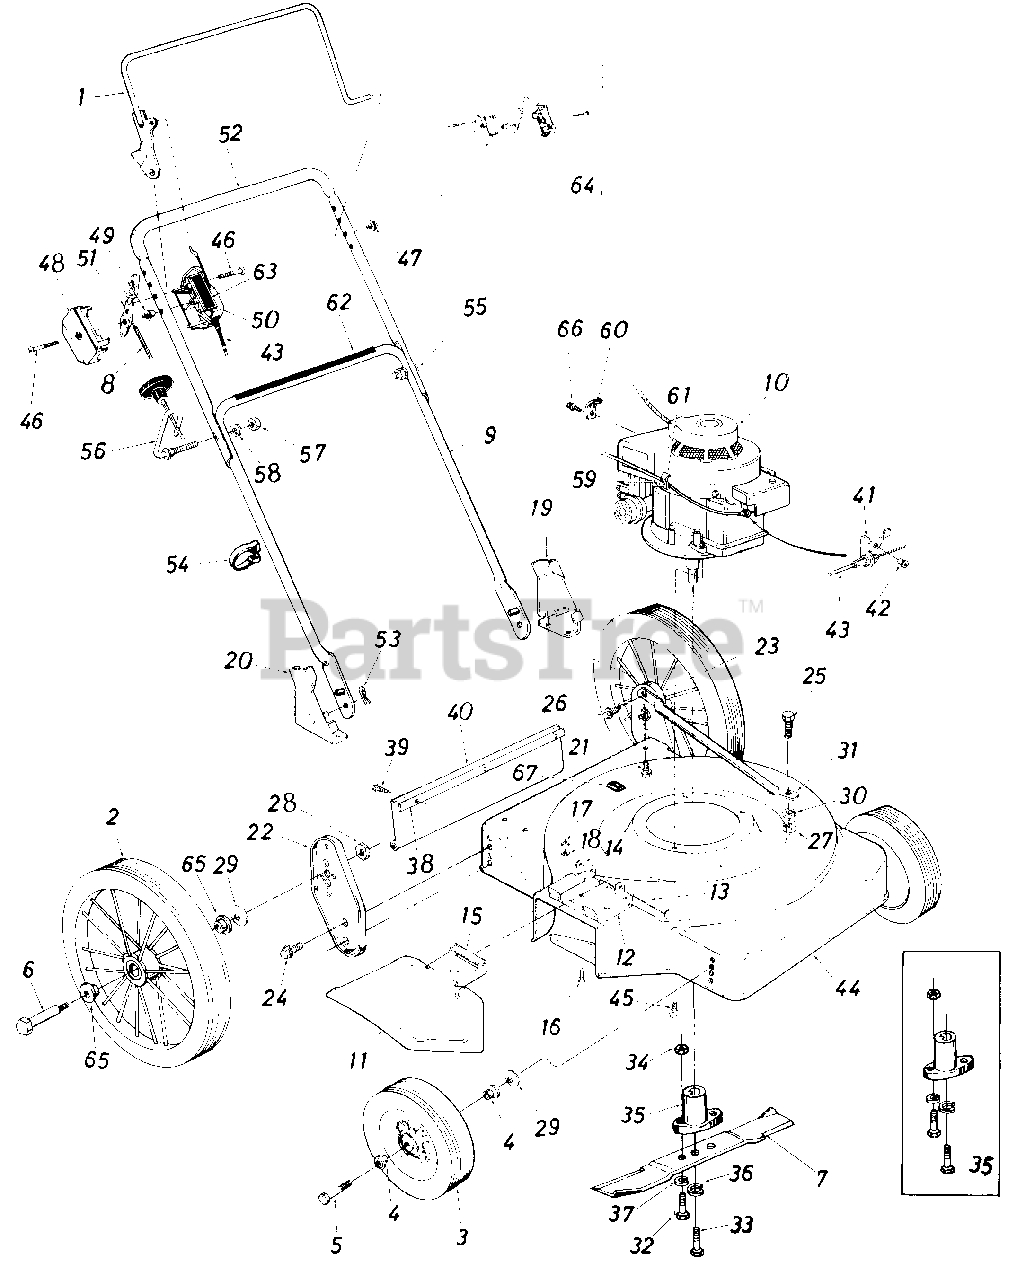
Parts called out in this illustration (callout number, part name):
1	Control Handle Ass'y.-R.H.
2	Rear Wheel Ass'y.-Comp. 14.0 x 1.75
4	Bearing
5	Axle Bolt-Front
6	Shoulder Bolt .50" Dia. x 2.62
7	22" Blade
8	Throttle Wire-43" Lg.
9	Lower Handle (Chrome)
10	Engine
11	Chute Deflector Ass'y.-Comp.
12	Adapter Plate
13	Pivot Pin
14	Push Nut 1/4" Rod
15	Torsion Spring
16	Hex Bolt 1/4-20 x .50" Lg.
17	Hex Nut 1/4 -20 Thd.
18	L-Wash. 1/4" I.D.
19	Handle Mount Brkt.-L.H.
20	Handle Mount Brkt.-R.H.
21	Hex Wash. Hd. "B" Tap Scr. 5/16-18 x .50" Lg.
22	Extension Brkt.-R.H.
23	Extension Brkt.-L.H.
24	Hex Sems Bolt 3/8-16 x .62"
25	Hex Bolt '14-20 x .62" Lg.
26	Hex Wash. Hd. "B" Tap Scr. 5/16-18 x .50" Lg.
27	Hex Nut 1/4-20 Thd.
28	Oval Nut 3/8-16 Thd.
29	Bell-Wash. .400" I.D. x .88" O.D.
30	L-Wash. 1/4" I.D.
31	Stabilizing Strut
32	Hex Bolt 5/16-24 x 1.00" Lg. (Grade 5)
33	Hex Bolt 3/8-24 x 2.25" Lg. (Grade 5)
34	Hex Nut 5/16-24 Thd.
35	Blade Adapter Kit
36	L-Wash. 3/8" I.D.-H.D.
37	L-Wash. 5/16" I.D.
38	Retaining Strip
39	Hex Wash. Hd. "AB"-Tap Scr. 1/4" x .62" Lg.
40	Rear Flap Ass'y.
41	Cable Bracket
42	Pop Rivet .156 Dia. x .379
43	Control Cable-Brake
44	22" Deck Ass'y.
45	Hex Wash. Hd. TT-Tap Scr. 3/8-16 x 1.00" Lg.
46	Truss Mach. "B"-Tap Scr. #12 x 1.50" Lg.
47	Cap Speed Nut 5/16" Rod
48	Control Panel Half
49	Control Disc Pin
50	Clutch Panel Half
51	Throttle Control Lever
52	Upper Handle (Chrome)
53	Intern. Cot. Pin 5/16" Dia.
54	Cable Tie
55	Curved Carriage Bolt 5/16-18 x 1.38" Lg.
56	Rope Guide Bolt
57	Hex Nut 5/16-18 Thd.
58	L-Wash. 5/16" I.D.
59	Hex B-Tap Scr. #10 x .38" Lg.
60	Casing Clamp
61	Casing Clamp
62	Instruction Label-Handle
63	Control Label-Throttle
64	Control Housing Comp.
65	Flange Bearing
66	Hex Wash. Hd. AB-Tap Scr. #8 x .38" Lg.
67	Plastic Plug
